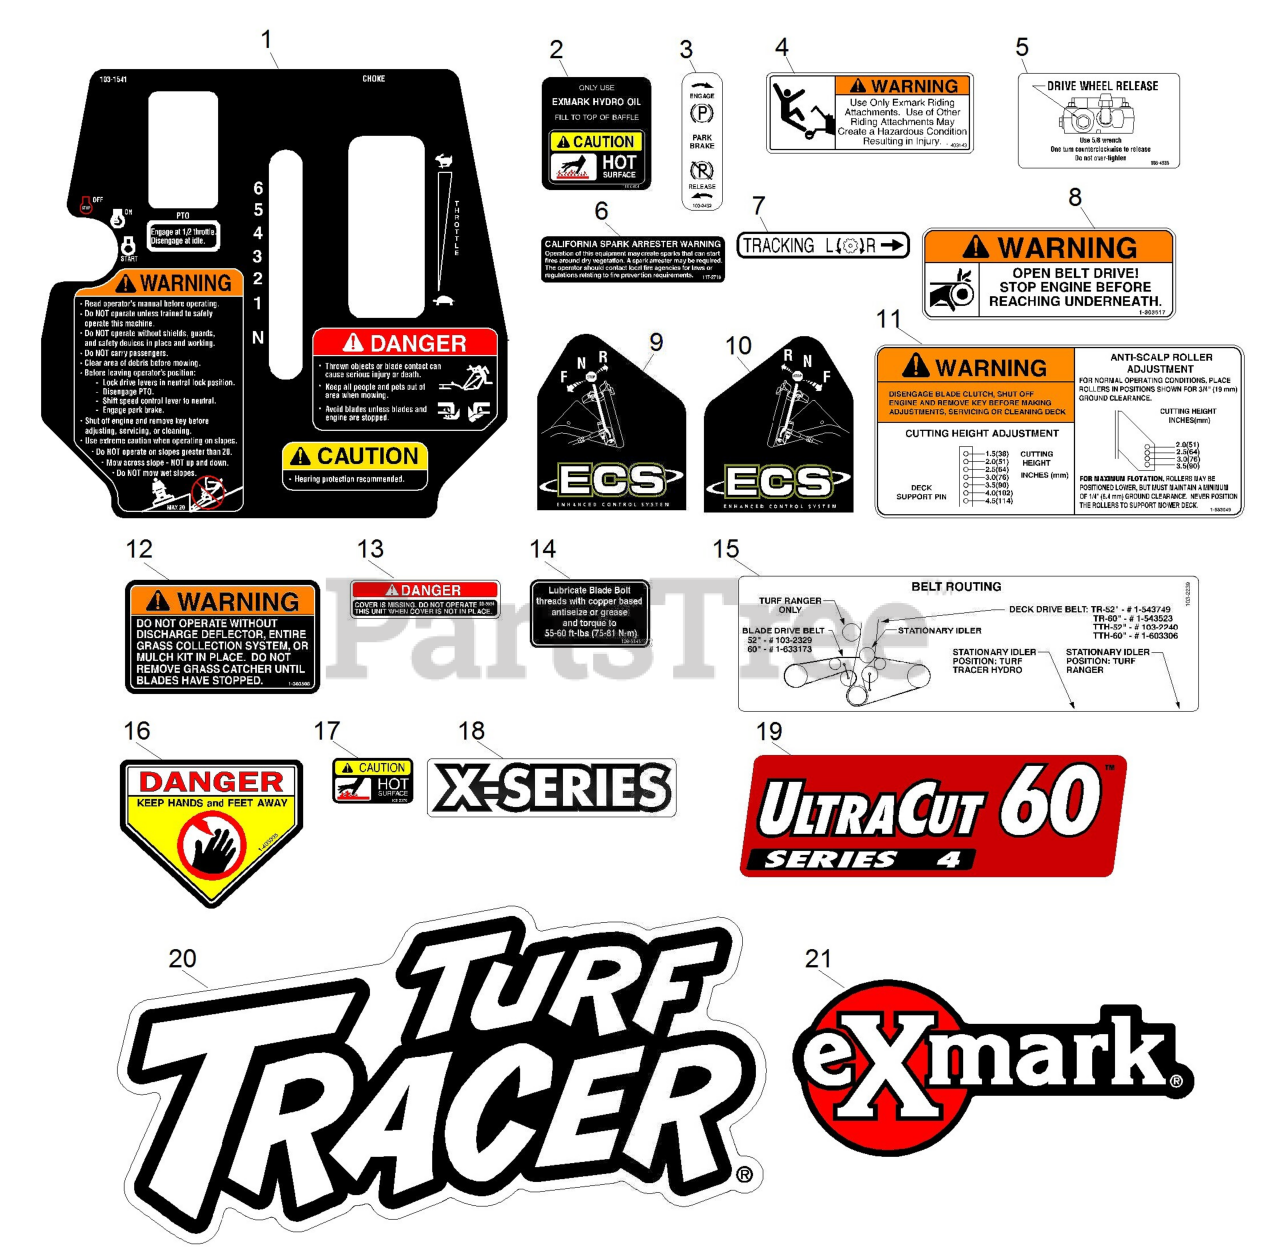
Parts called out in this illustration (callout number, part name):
1	DECAL,TTH ECS CONSOLE
2	DECAL-HYDRAULIC TANK
3	DECAL,PARKING BRAKE
4	DECAL,SULKY WARNING
5	DECAL,DRIVE RELEASE
6	DECAL-ARRESTER, SPARK
7	DECAL,TRACKING ADJUST
8	DECAL,BELT DRIVE
9	DECAL,LH ECS INSTRUCTION
10	DECAL,RH ECS INSTRUCTION
11	DECAL,ANTI SCALP
12	DECAL-WARNING, DISCHARGE
13	DECAL-COVER, MISSING
14	DECAL,BOLT TORQUE
15	DECAL,BELT ROUTING
16	DECAL-DANGER
17	DECAL-CAUTION
18	DECAL-X-SERIES
19	DECAL,ULTRACUT 60 SERIES
20	DECAL,TTH MODEL
21	DECAL,EXMARK LOGO
